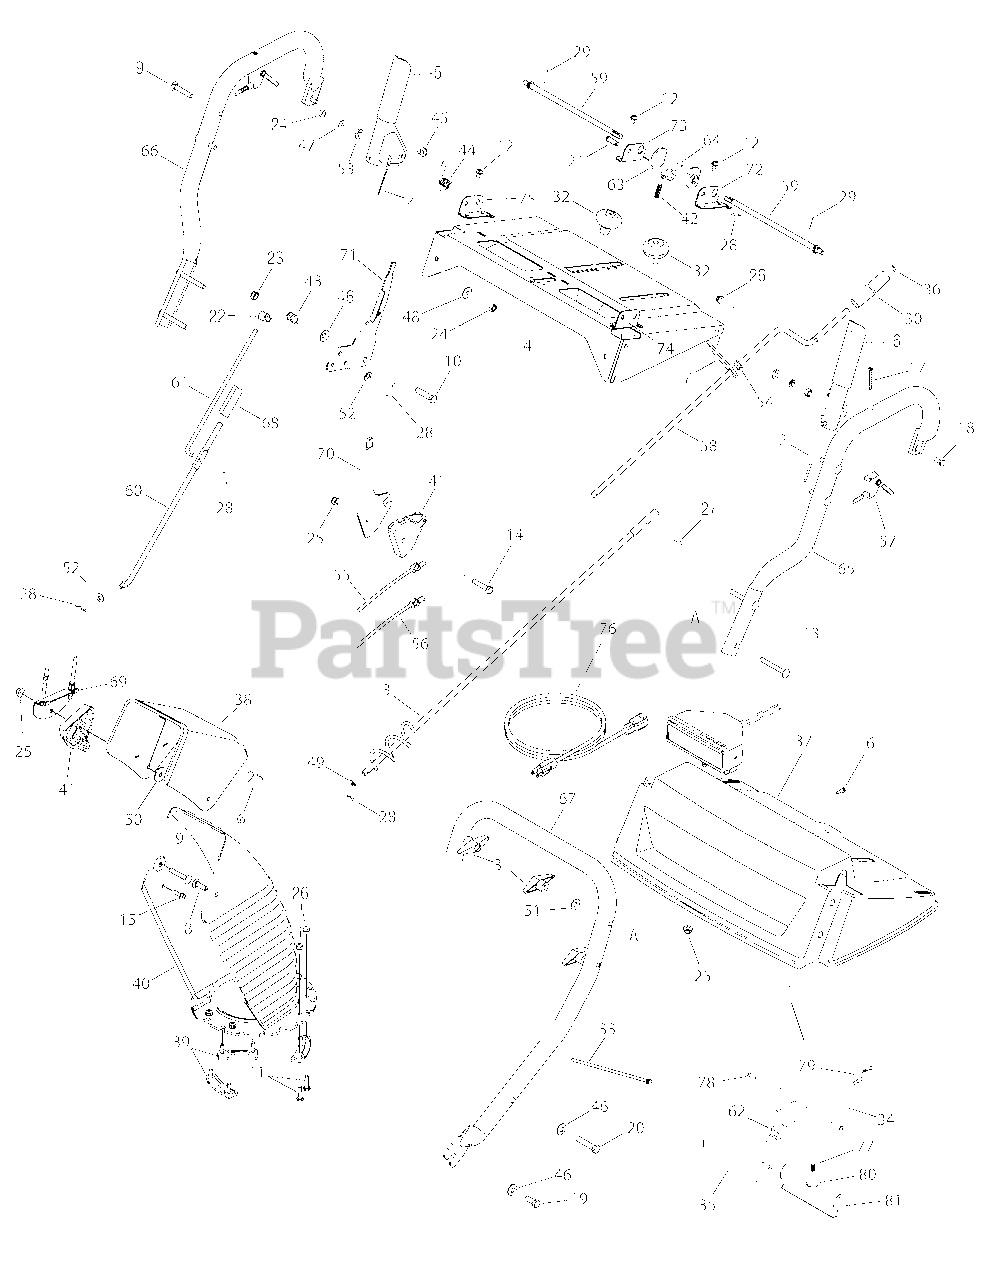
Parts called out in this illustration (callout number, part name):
1	Light Assembly w/ Harness
2	Cable Ass’y, Auger/Drive
5	Handle, Engage, RH
6	Handle, Engage, LH
8	Screw, Carr, 5/16-18 x 1.0
9	Screw, Carr., 5/16-18 x 1.75
10	Screw, Hex, 3/8-24 x 1.5
11	Screw, Hex, 1/4-20 x 1.0
12	Screw, Hex, 1/4-20 x .5
13	Screw, Carr., 5/16-18 x 2.5
14	Screw, Hex, 5/16-18 x 1.5
15	Screw, Hx,1/4-15 x .75
16	Screw, #10-16 x .625
17	Screw, #10-24 x 1.75
18	Screw, Hex, 1/4-20 x .75
19	Screw, Hex Lock, 3/8-16 x 1.0 Gr5
20	Screw, Hex Lock, 3/8-16 x 2.0 Gr5
21	Pin, Clevis, .312 x 1.0
22	Ferrule, 5/16-18 x .312 Dia
23	Nut, Insert, 3/8-24
24	Nut, Hex Patch Lock, 5/16-18 Gr5
25	Nut, Flnge Lk, 5/16-18
26	Nut, Hex Flange, 1/4-20
27	Pin, Internal Cotter
28	Pin, Internal Cotter
29	Pin, Cotter, 3/32 x .75
30	Knob, Crank
31	Knob,Wing Nut, 5/16-18
32	Knob, Shift
33	Tie, Cable
34	Housing, Lamp
35	Housing, Lamp w/Lens
36	Cap, Push, 3/8
37	Panel, Handle
38	Chute, Upper, 6.0
39	Flange Keeper, Chute
40	Chute, Lower
41	Cbl. Guide, Chute Tilt
42	Spring, Compression
43	Spring, Compression
44	Spring, Torsion
45	Bumper, Rubber
46	Washer, Bell, .375 x .87 x .063
47	Washer, Lock, 5/16
48	Washer, Flat, .349 x .879 x .063
49	Washer,Fl., .375 x .738 x .063
50	Washer, Fl, .344 x 1.125 x .12
51	Washer, Bell, .34 x .872 x .06
52	Washer, Fl, .344 x .688 x .065
53	Washer, Fl, .35 Sq x .72 x .134
54	Bushing, Plastic, .38 ID
55	Cable, Chute Control, 66"
56	Cable, Chute Control w/Clip,
57	Cable Assembly, Trigger
60	Rod, Lower Shift
61	Rod, Upper Shift
62	Lamp, Halogen, #890-12V-27W
63	Cam, Handle Lock
64	Pawl, Handle Lock
68	Connector, Shift Rod
76	Extension Cord, 110V
77	Screw, Carriage, 5/16-18 x .75
78	Screw, Pan Head Machine
79	Harness, Electrical
81	Bracket, Lamp Mounting
